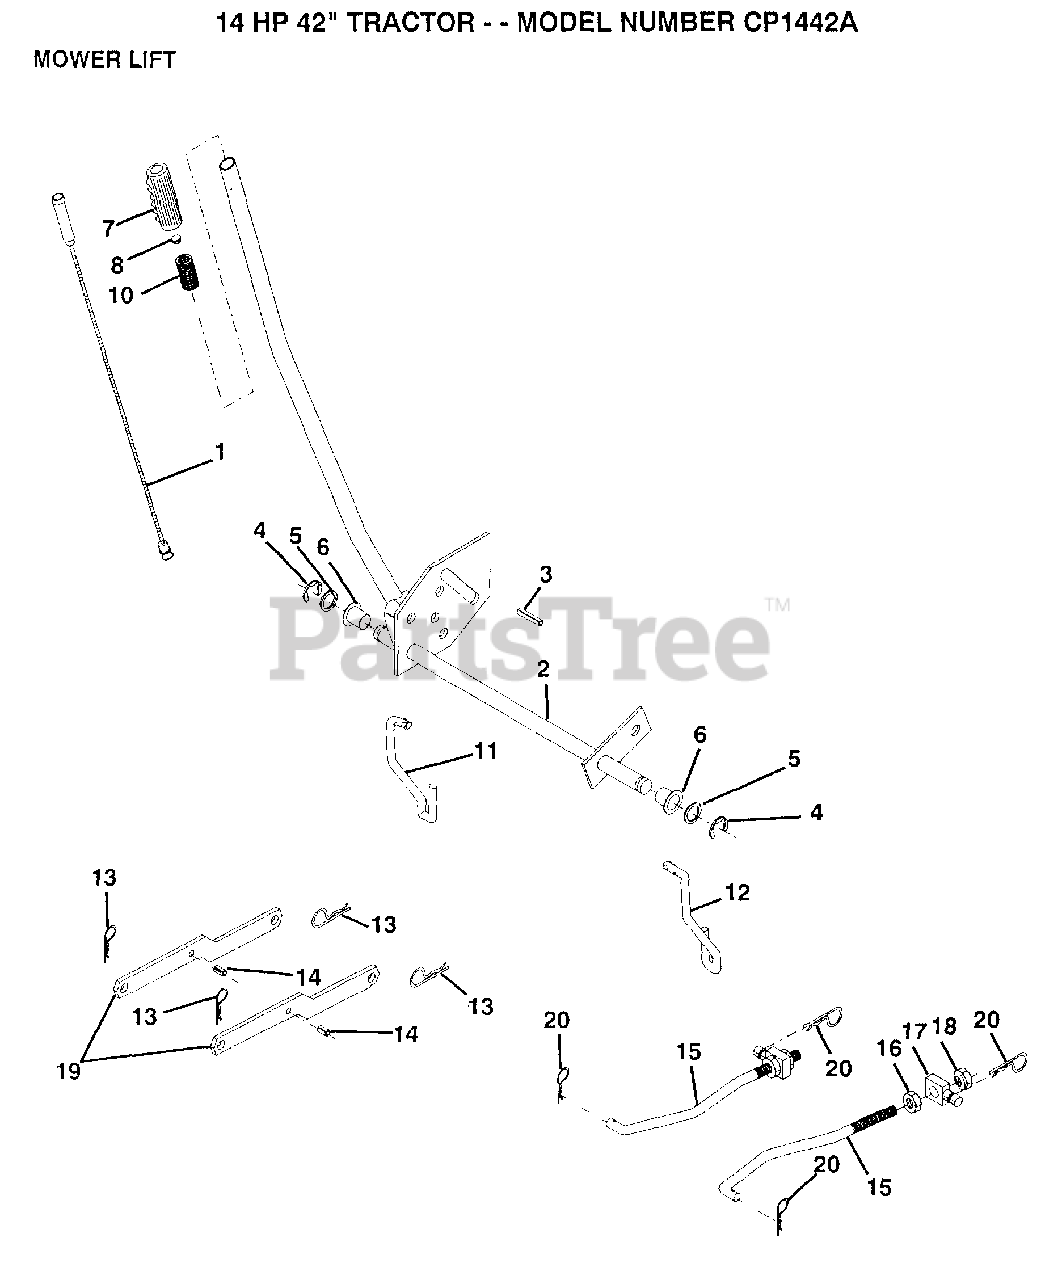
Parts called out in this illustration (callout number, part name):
1	WIRE ASM
3	PIN-GROOVE LT
5	WASHER
6	NYLON BEARING
7	GRIP
11	LINK LIFT LH
12	LIFT LINK RH
14	"PIN,SPRING"
15	LINK.FRONT
16	NUT
17	TRUNION
18	NUT.LK.W/WSH.1/2.
20	RETAINER.SPRING
